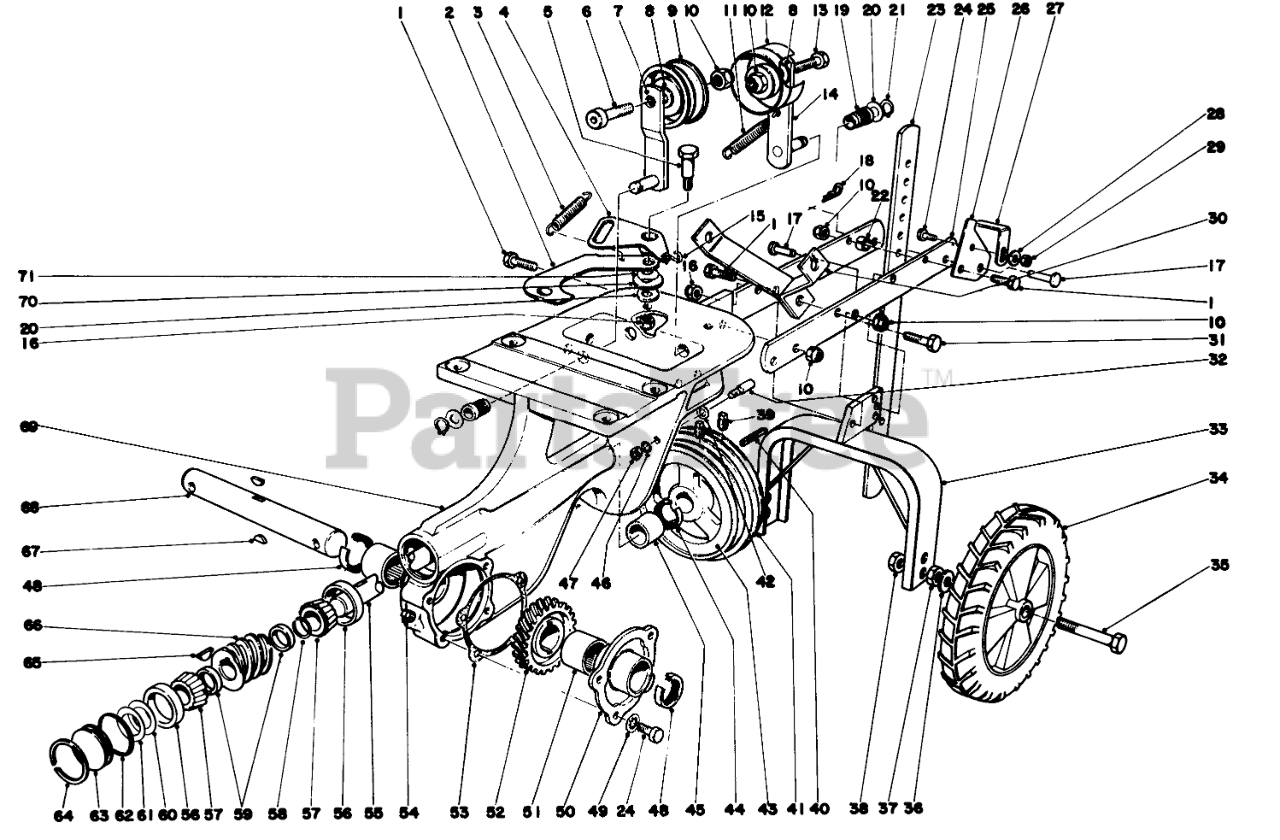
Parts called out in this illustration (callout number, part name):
1	SCREW-HH
2	Rev. Link
3	Spring
4	Bellcrank
5	SCREW-SHOULDER, HH
6	Socket Hd. Capscrew
7	IdlerArm
8	WASHER-FLAT
9	PULLEY IDLER
10	NUT-LOCK, CONE
11	Spring
12	IDLER PULLEY
13	SCREW-HH
14	Idler
15	S Hook
16	NUT-LOCK, CONE
17	TINE PIN
18	PIN-COTTER, HAIR
19	Bearing Idler
20	WASHER-PLAIN
21	RING-RETAINING, EXT
22	Spacer
23	DEPTH GAGE
24	SCREW-HH
25	Drawbar
26	Hinge Latch
27	Drag Bar Latch
28	WASHER-FLAT
29	NUT-LOCK, CONE
30	Handle Support
31	SCREW-HH
32	Belt Guide
33	Wheel Bracket
34	Wheel
35	SCREW-HH
36	WASHER-FLAT
37	NUT-JAM
38	1/2-13 CONELOCK NUT
39	SCREW-SET, HSH
40	KEY-SQUARE
41	Pulley
42	WASHER-FLAT
43	Pulley
44	SEAL-OIL
45	BUSHING
46	WASHER-LOCK/EXT
47	NUT-JAM
48	SEAL-OIL
49	WASHER-LOCK
50	Cover
51	Needle Bearing
52	WORM WHEEL
53	GASKET
54	PLUG-PIPE, SQH
55	WORM SHAFT
56	BEARING-ROLLER, CUP
57	BEARING-CONE
58	RETAINER RING
59	SPACER
62	O-RING
64	INTRNL RETAINING RING
65	KEY-WOODRUFF
66	WORM GEAR
67	KEY-WOODRUFF
68	WORM WHEEL SHAFT
69	Chassis
70	WASHER-FLAT
71	7/16 SPRING WASHER
